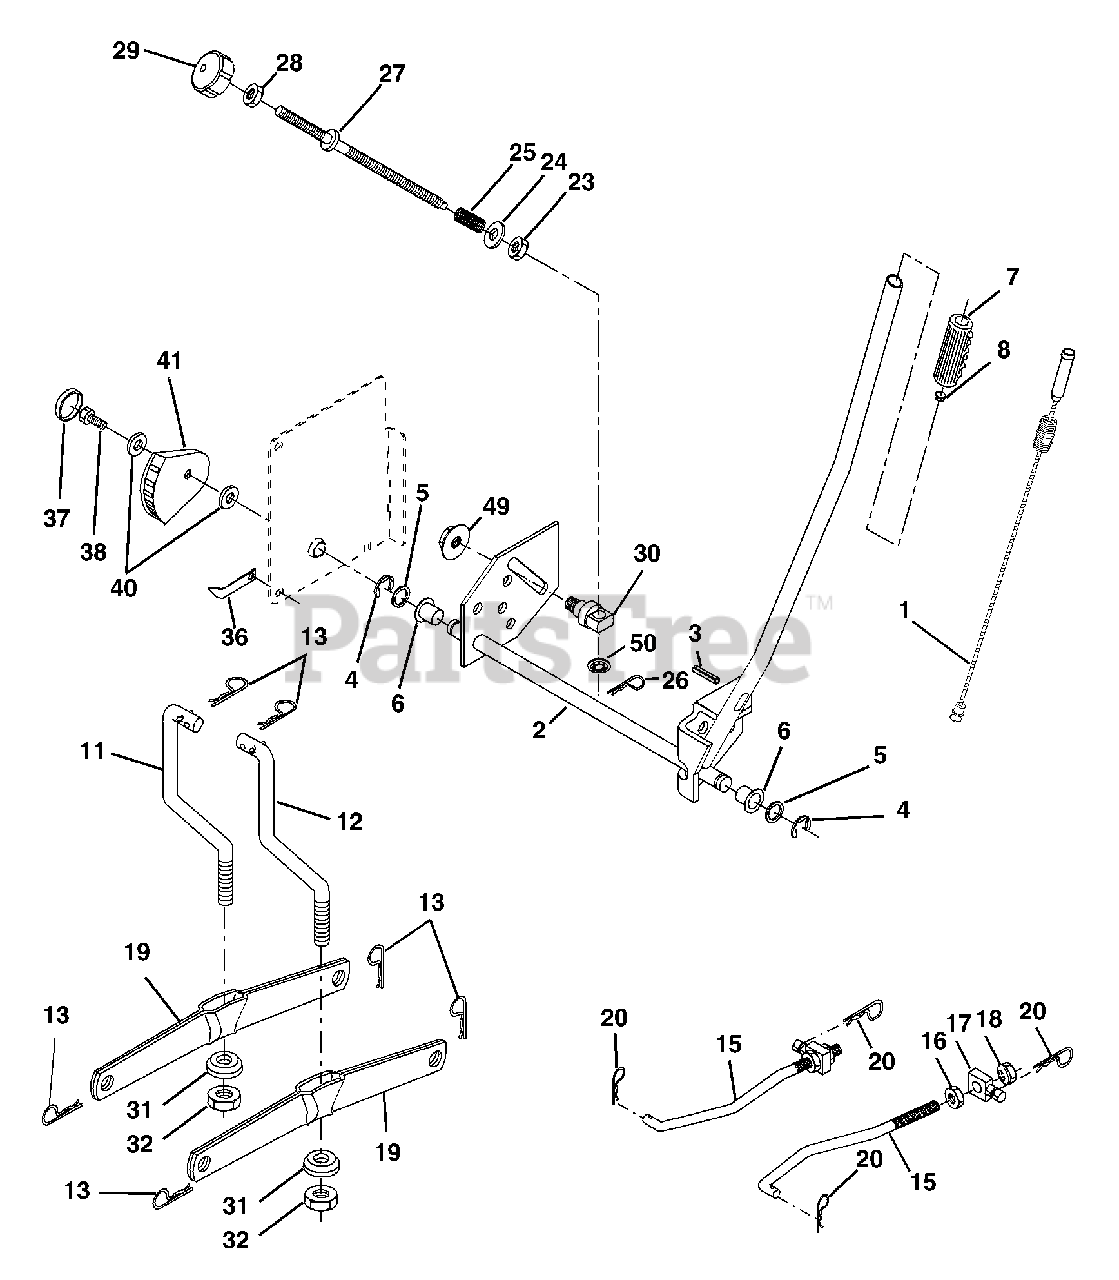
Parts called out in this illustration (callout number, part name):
1	Wire Asm Inner/Sprg W/plunger LT
2	Shaft Asm Lift RH w/Inf
3	Pin Groove 1 500 Zinc
4	E Ring #5133-62
5	Washer 21/32 x 1 x 21 Ga
6	Bearing Nylon Blk 629 Id
7	Grip Handle
8	Button Plunger
11	Link Lift LH Fixed Length
12	Link Lift RH Fixed Length
13	Retainer Spring
15	Link Front
16	Nut Jam Hex 1/2-13 Unc
17	Trunnion
18	Nut Lock W/Wsh 1/2-13 Unc
19	Arm Suspension Rear
20	Retainer Spring
23	Nut Special
24	Washer 13/32 x 5/8 x 16 Ga
25	Spring 2-1/8"
26	Retainer Clip
27	Rod Adj Lift Zinc 7.49 Wrk Lg
28	Nut Hex Jam 3/8-16 Unc
29	Knob Inf 3/8-16 Unc Blk W/sym
30	Trunnion Infin Height
31	Bearing Pvt Lift
32	Nut Crownlock 3/8 - 24
36	Pointer Height Indicator
37	Plug Hole Blk 1.485/1.515 Dia.
38	Screw 5/16-18 x 1
40	Washer 11/32 x 1-1/2 10 Ga.
41	Indicator Height STLT
49	Nut Hex Flange Lock
50	Nut PUsh Phos & Oi
